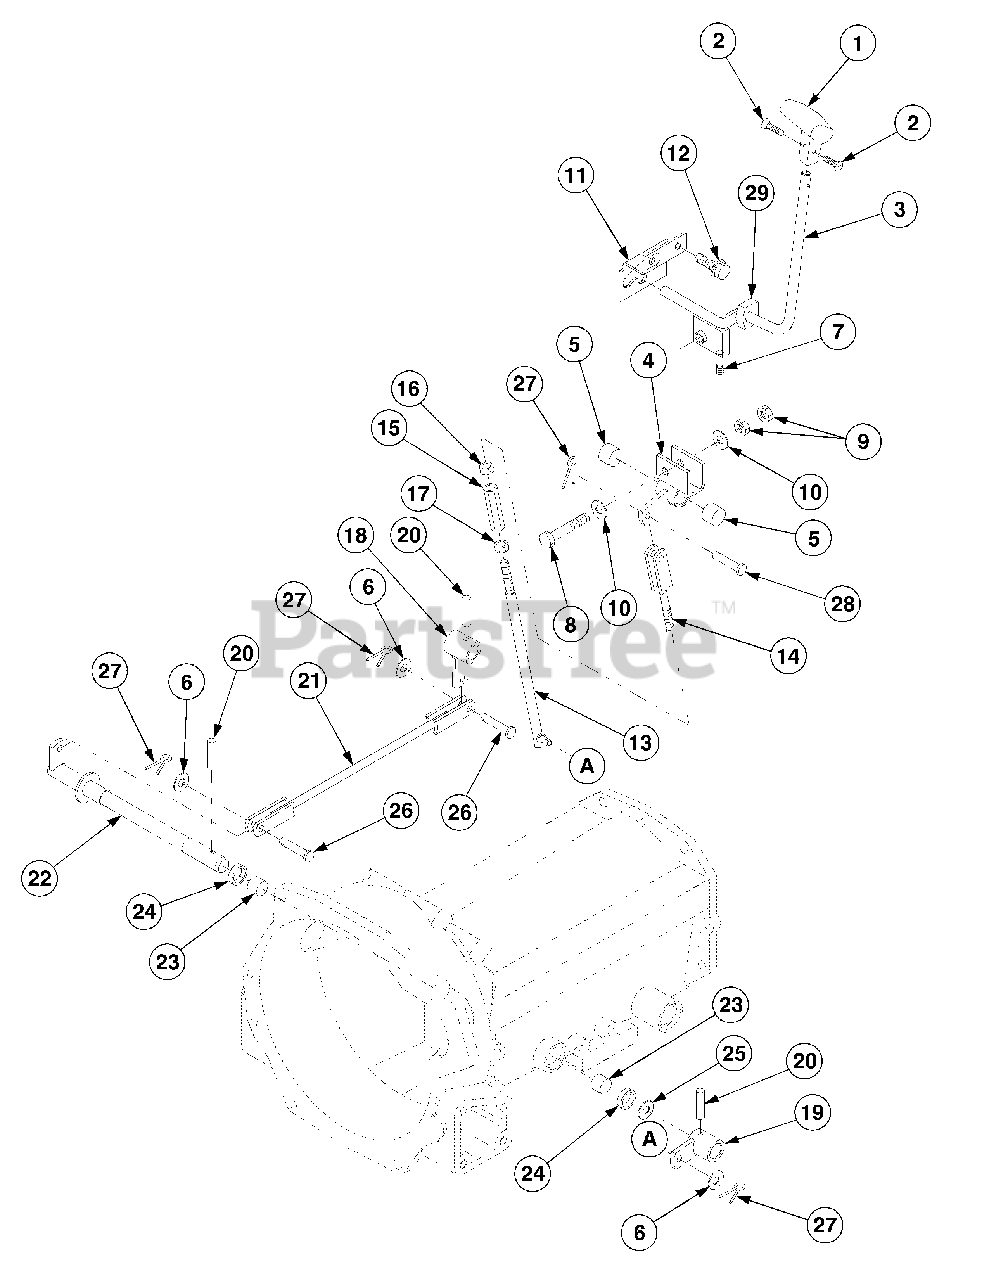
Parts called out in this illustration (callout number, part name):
3	Lever, Shuttle
12	Bolt, w/Washer
19	Link, Shuttle
